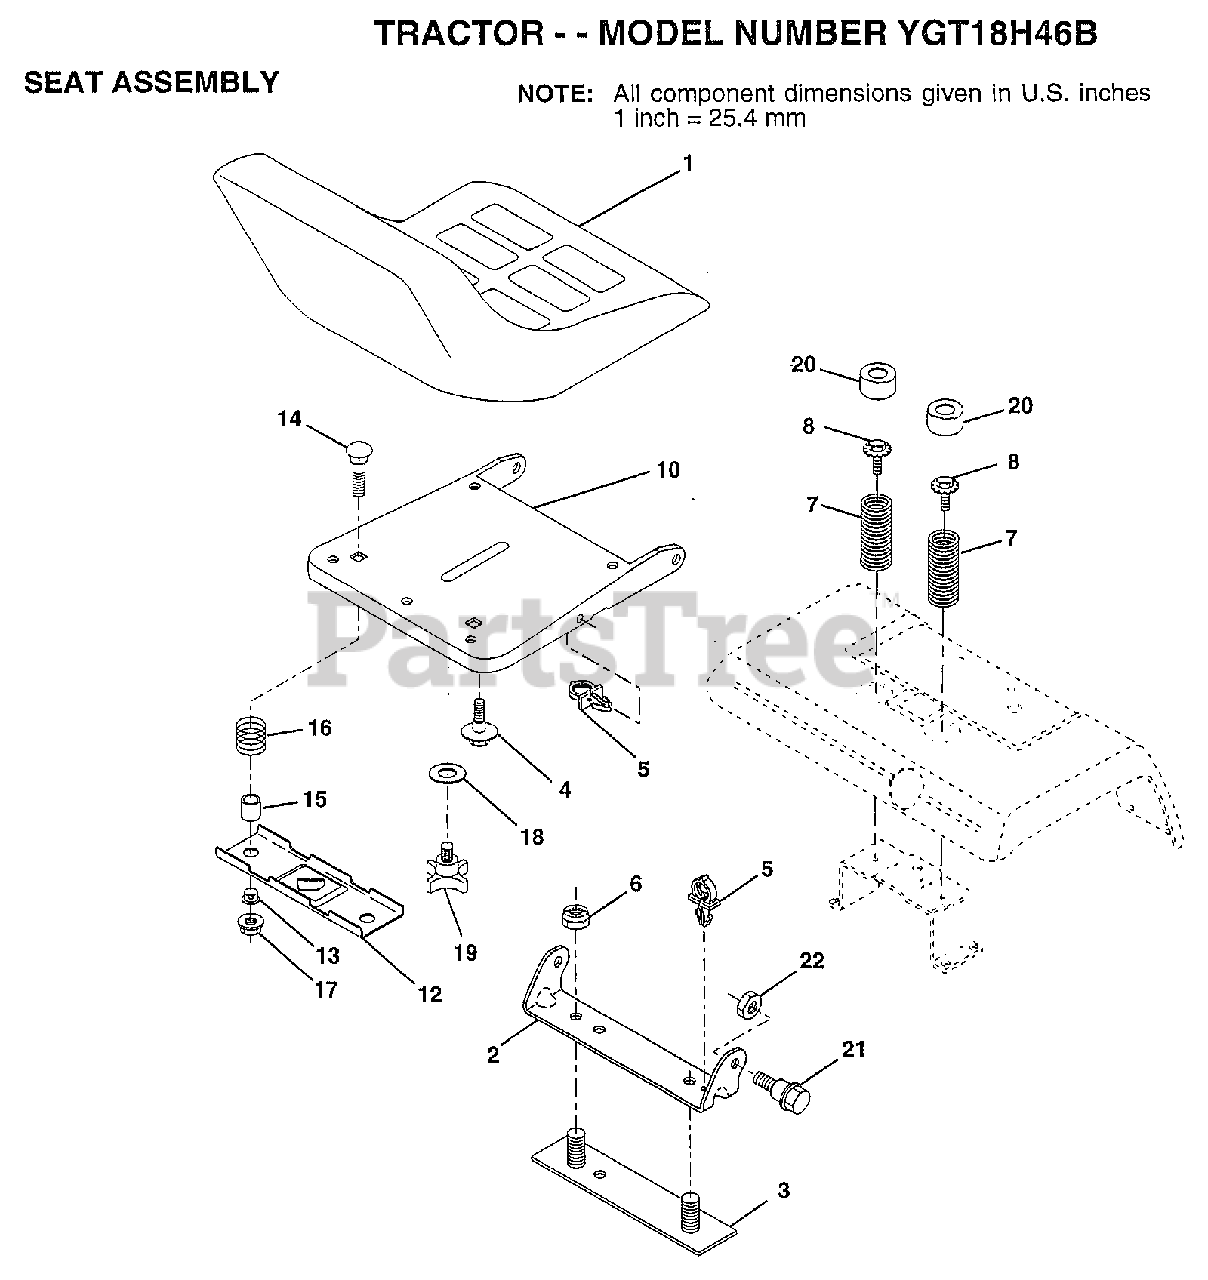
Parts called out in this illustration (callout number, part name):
2	BRACKET PVT SEAT
3	STRAP ASM FENDER
4	"BOLT,SHOULDER"
5	CLIP.PUSH-IN.HING
6	NUT
7	SPRING COMPRESSIO
8	BOLT.5/16-18.UNC
10	PAN-SEAT
12	BRKT SWITCH
13	BUSHING
14	BOLT-RD HD SQ NK
15	SPACER SPLIT
16	SPRING COMPRESSED
18	WASHER
19	"KNOB 1/2"" YT"
20	CAP SPRING
21	"BOLT,SHOULDER"
22	NUT
